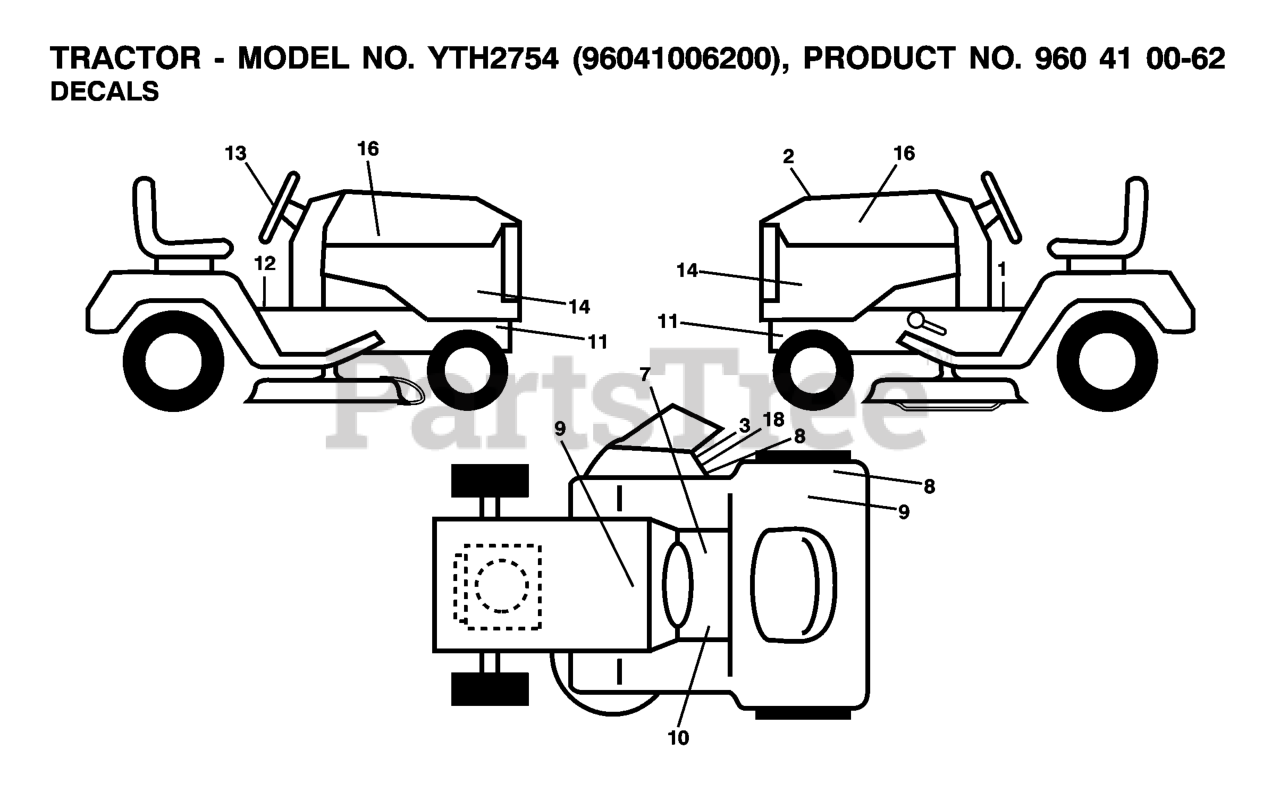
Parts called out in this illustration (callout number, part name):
1	DECAL
2	DECAL.HOOD.TOP.INSERT.
3	DECAL.INTERNATIONL.CUTFINGER
7	LABEL
8	DECAL
9	DECAL 80 DBA
10	DECAL
12	DECAL PARK BRAKE
13	DECAL.WHEEL.STRG.LGN.H
16	DECAL.HOOD.NAMELOGO.HUSQ
18	DECAL, DEFLECT WARNING
